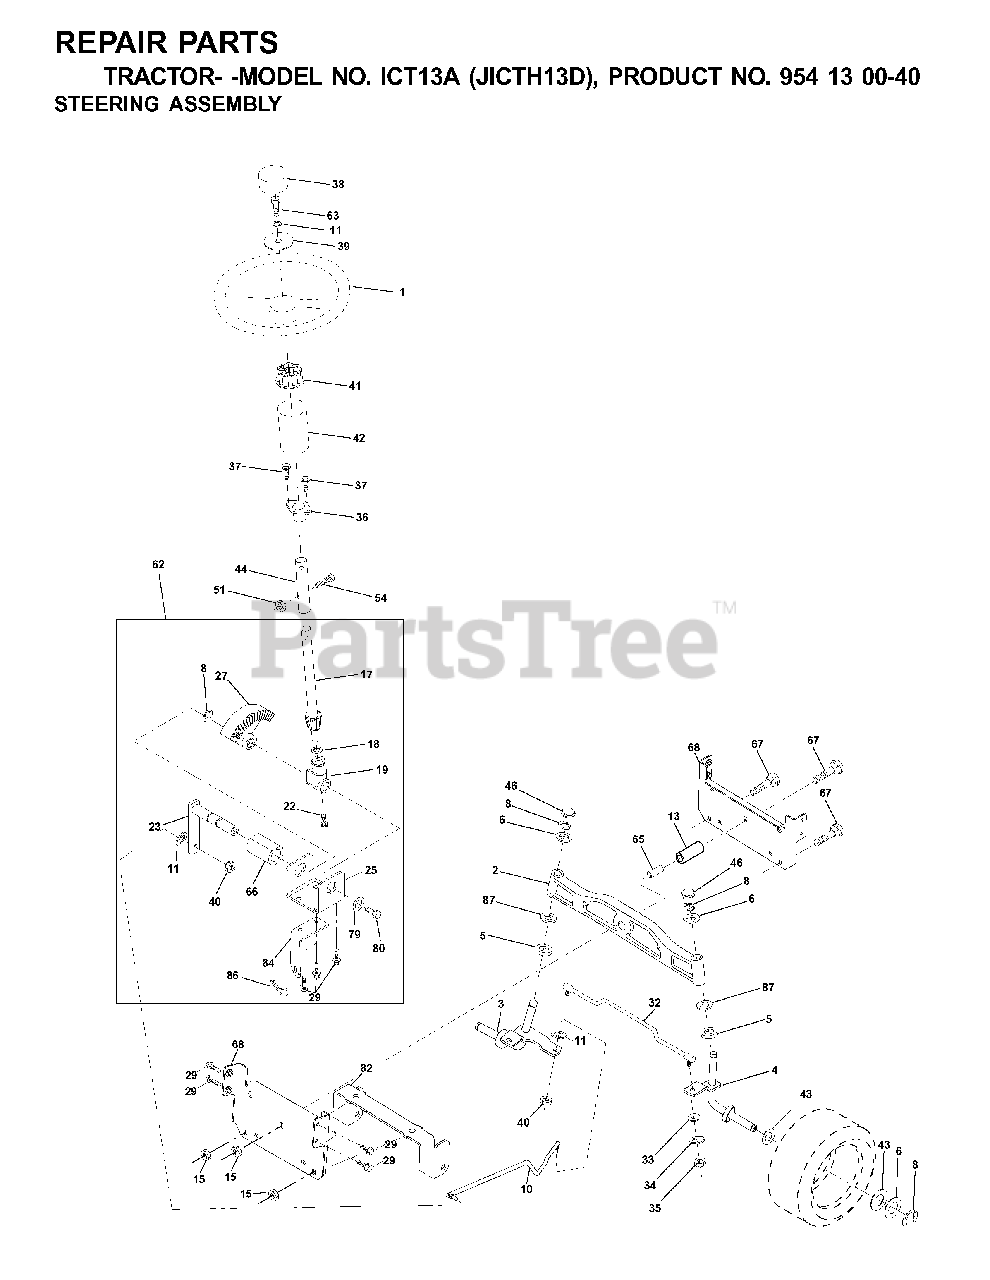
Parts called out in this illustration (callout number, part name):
2	AXLE ASM
3	SPINDLE.ASM.LH.15"TIRES
4	SPINDLE.ASM.RH.15"TIRES
8	RING CLIP
10	DRAGLINK.15".TIRES
11	WASHER, LOCK 3/8
13	TUBE, PIVOT AXLE
15	NUT
17	SHAFT ASM STEERING
18	THRUST WASHER
19	STEERING SHAFT SUPPORT
22	SCREW.HX.WSH.HD
23	SHAFT ASSY PITTMAN
25	BRACKET STEERING
27	GEAR.SECTOR
29	SCREW 3/8-16X3/4
32	ROD.ASM.TIE.BALL.JOINT.NOVAN
33	WASHER M
34	LOCKWASHER
35	NUT, CROWNLOCK
36	BUSHING, STEERING
39	WASHER 13/32 X 2-3/8 X 12 GA
40	GRIPCO NUT
41	STEERING WHEEL ADAPTOR
42	BOOT.STEERING.SHAFT.BLACK
44	EXT SHAFT STEERING
46	CAP.SPINDLE
51	NUT.71038.31-18.HEX.NYLOCK
54	BOLT.5/16-18X1-1/4 FULL.THREAD
65	SPACER BRACE AXLE
66	BEARING ARM
67	BOLT
68	BRACE.AXLE.15"TIRES
80	BOLT.HX.NYLON3/8-16X
82	BRACKET
86	SPRING.RETAINER.YELLOW.ZINC
87	WASHER, FLAT .781 X 1 1/2"
